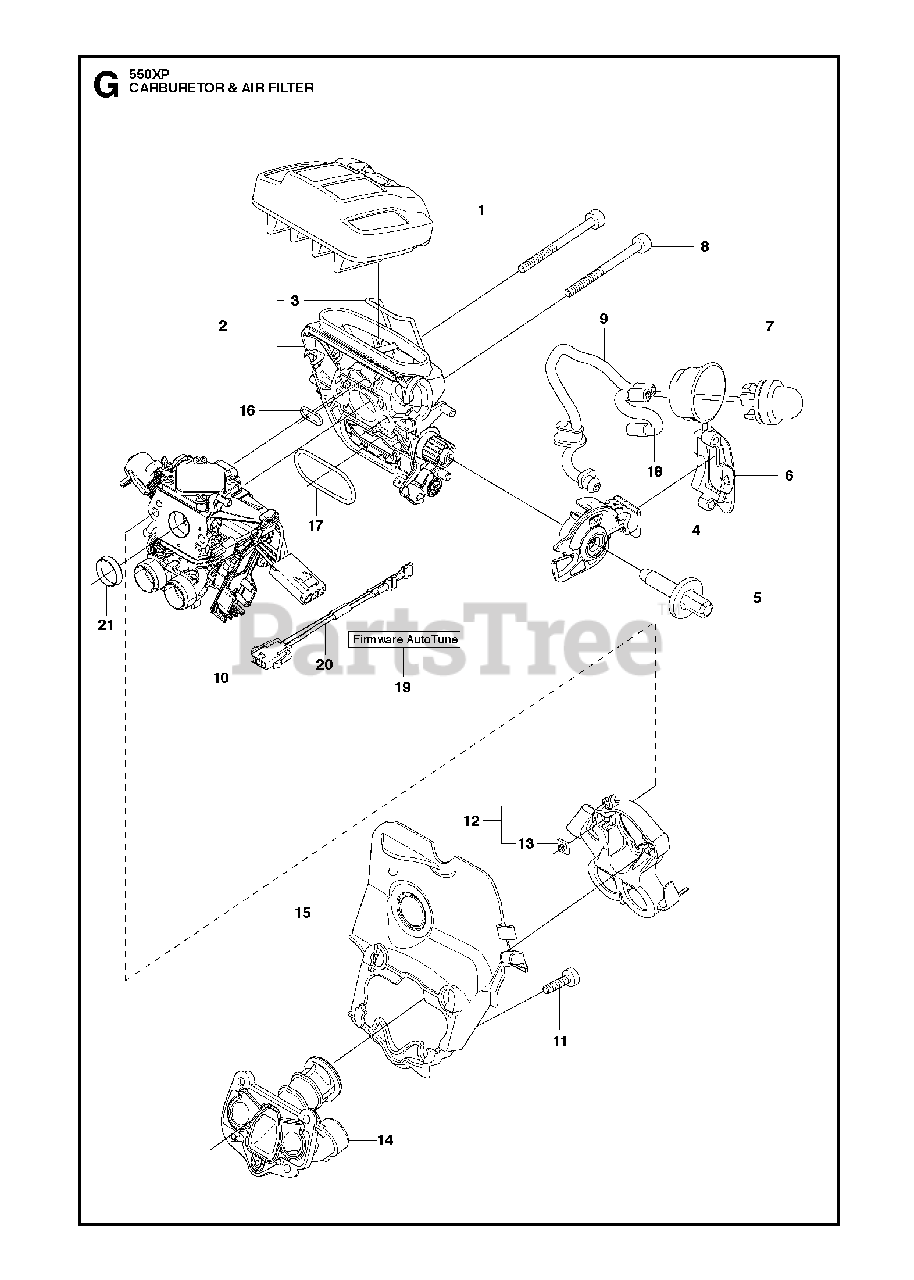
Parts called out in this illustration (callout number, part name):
1	AIR FILTER
1	AIR FILTER ASSY
1	Air Filter Assembly
2	FILTER HOLDER ASSY
3	SHACKLE
4	CHOKE CONTROL ASSY CHOKE/STOP
7	AIR PURGE BUBBLE
9	VENTILATING HOSE,KIT
9	Fuel Hose
10	CARBURETTOR KIT
11	SCREW IHSCM
13	NUT
14	INLET PIPE ASSY
15	INTERMEDIATE WALL
19	Husqvarna TBD
20	WIRING ASSY
21	SUPPORT SLEEVE
